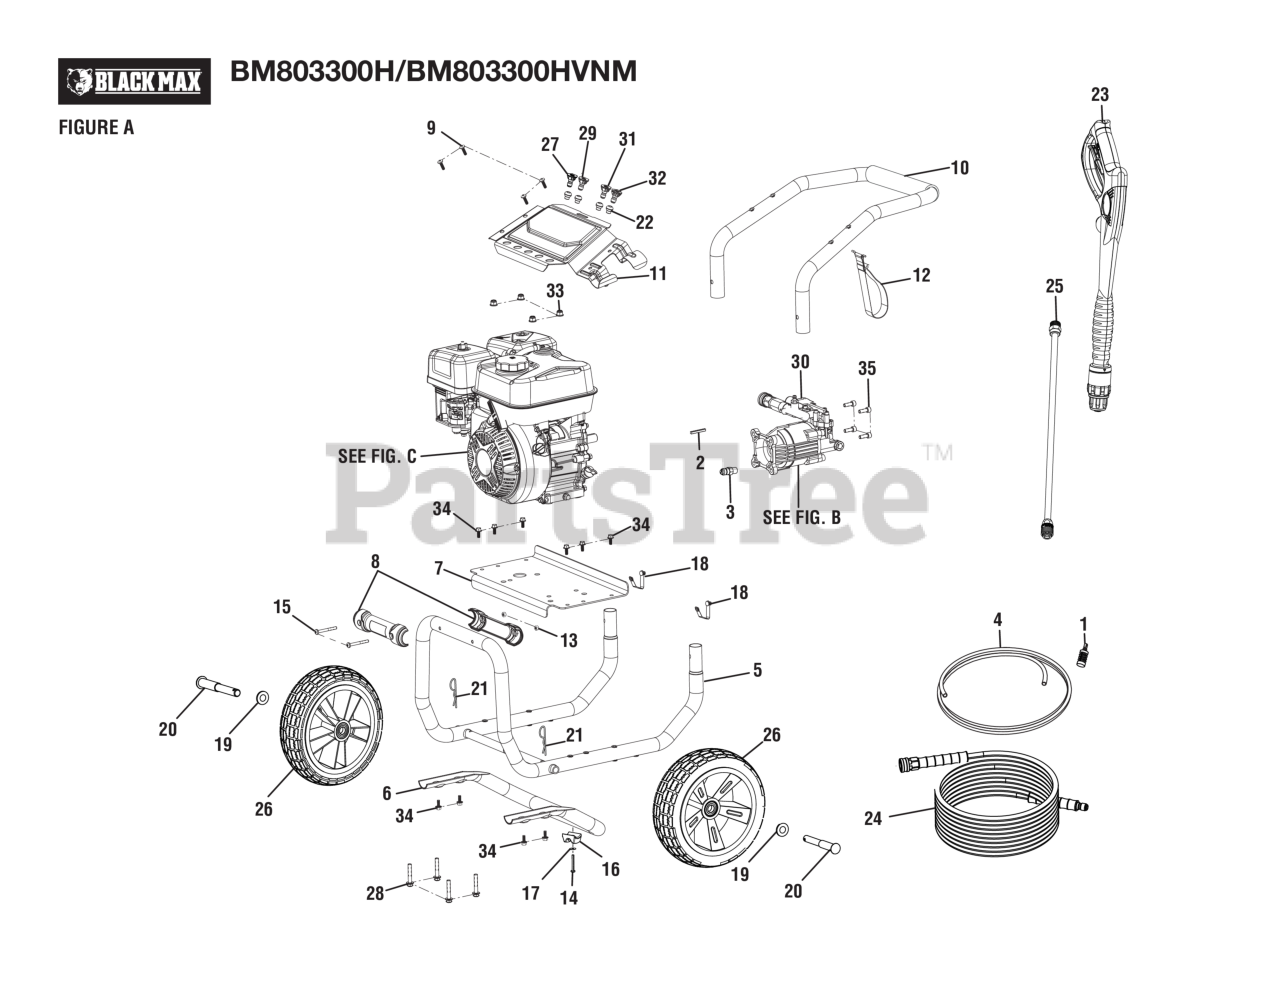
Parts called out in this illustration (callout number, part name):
1	Detergent Injection Filter
2	Output Shaft Key (3/16 in. x 40 mm)
3	Thermal Release Valve.
4	Detergent Injection Tube
5	Main Frame Assembly
6	Rear Frame Assembly
7	ENGINE PLATE
8	Lower Frame Cover
9	Screw (M6 x 20 mm, Phillips Hd.)
10	Handle Assembly
11	Performance Panel w/Wand Holder
12	Hose Holder Strap
13	Lock Nut (M6 x 1)
14	Screw (M6 x 1.25in., T30 Torx Pan Hd.)
15	Screw (M6 x 55 mm, T3 Torx Pan Hd.)
16	Rubber Foot
17	Washer (1/4 in.)
18	Lock Button w/Spring Clip.
19	Washer (1/2 in.)
21	Hitch Pin
22	Nozzle Grommet
23	Trigger Handle
24	Hose (35 ft.)
25	Extension Wand
27	Nozzle, 0 deg
28	Bolt (M8 x 1.25 x 40 mm, Flange Hd.)
29	25 deg Nozzle
31	40 deg Nozzle
32	Soap Nozzle
33	Lock Nut (M8 x 1.25 mm, Flange)
34	Flange Bolt (M6 x 1 x 16 mm, Hex Hd.)
35	Screw (5/16-24 x 23 mm, Hex Soc. Cap Hd.)
